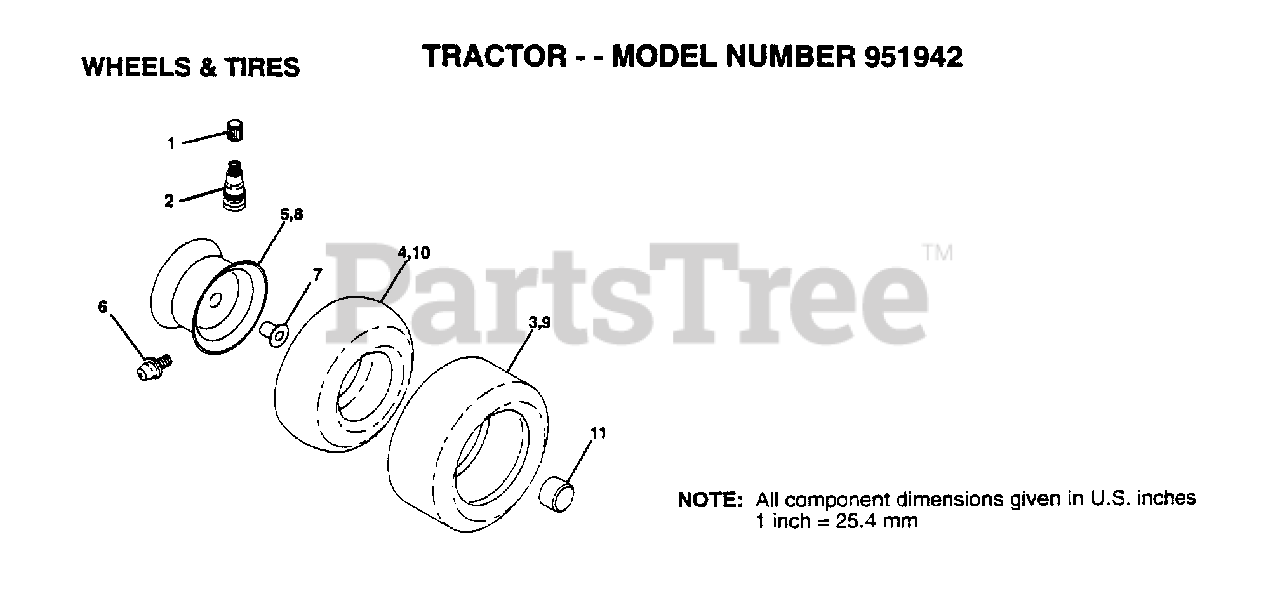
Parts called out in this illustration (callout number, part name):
1	VALVE CAP
2	VALVE STEM LT
4	TUBE.16X6.5/7.5-8
5	RIM.FRONT.
6	FITTING LT
7	"FLANGE, BEARING"
8	"WHEEL,REAR"
10	TUBE.23X8/10-12
11	HUB CAP
